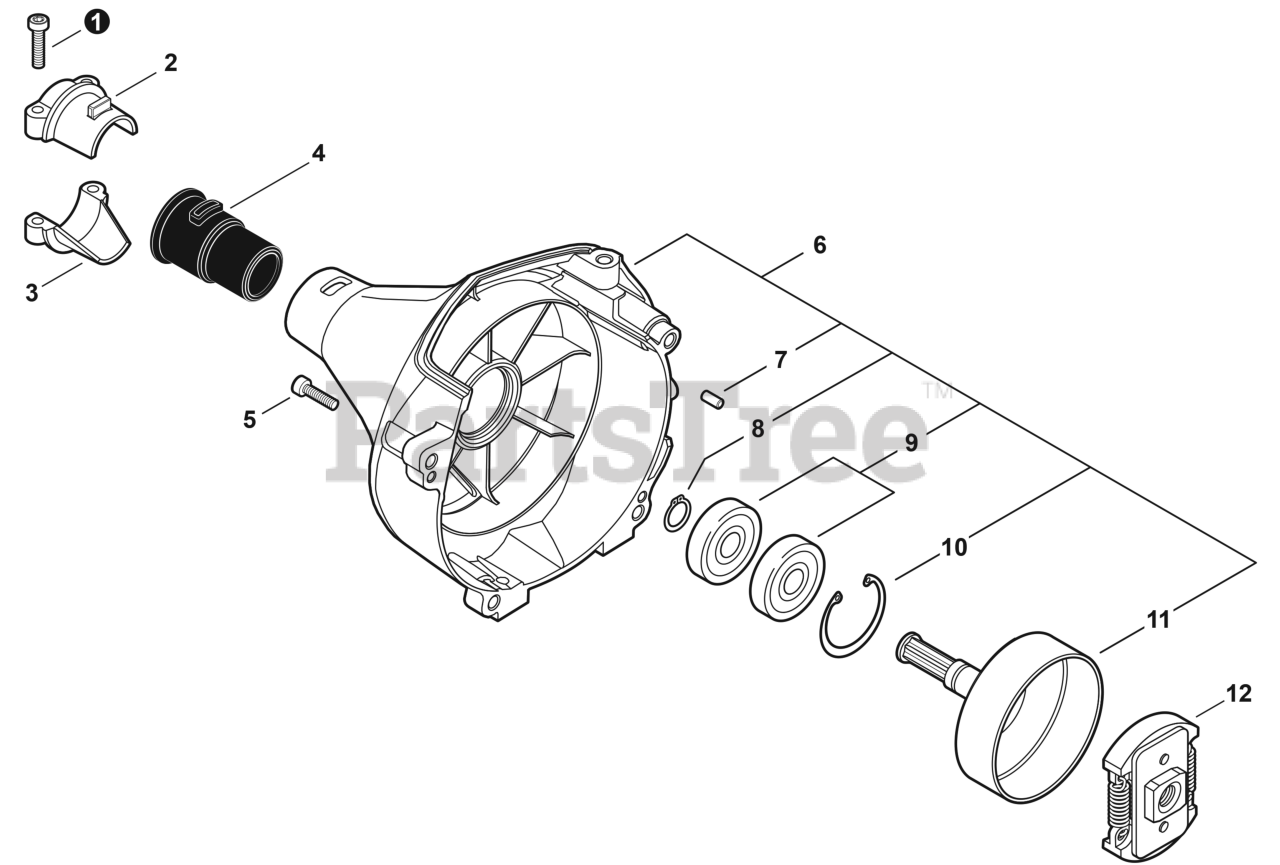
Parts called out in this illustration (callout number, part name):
1	BOLT, TORX 5x20
2	HOLDER, MAIN PIPE - UPPER
3	HOLDER, MAIN PIPE - LOWER
4	CUSHION 25
5	BOLT, TORX 4x16
6	COVER ASSY, FAN
7	PIN, LOCATING 4
8	RING, SNAP 12
9	BEARING, BALL 6001
10	RING, SNAP 28
11	DRUM, CLUTCH
12	CLUTCH ASSY
